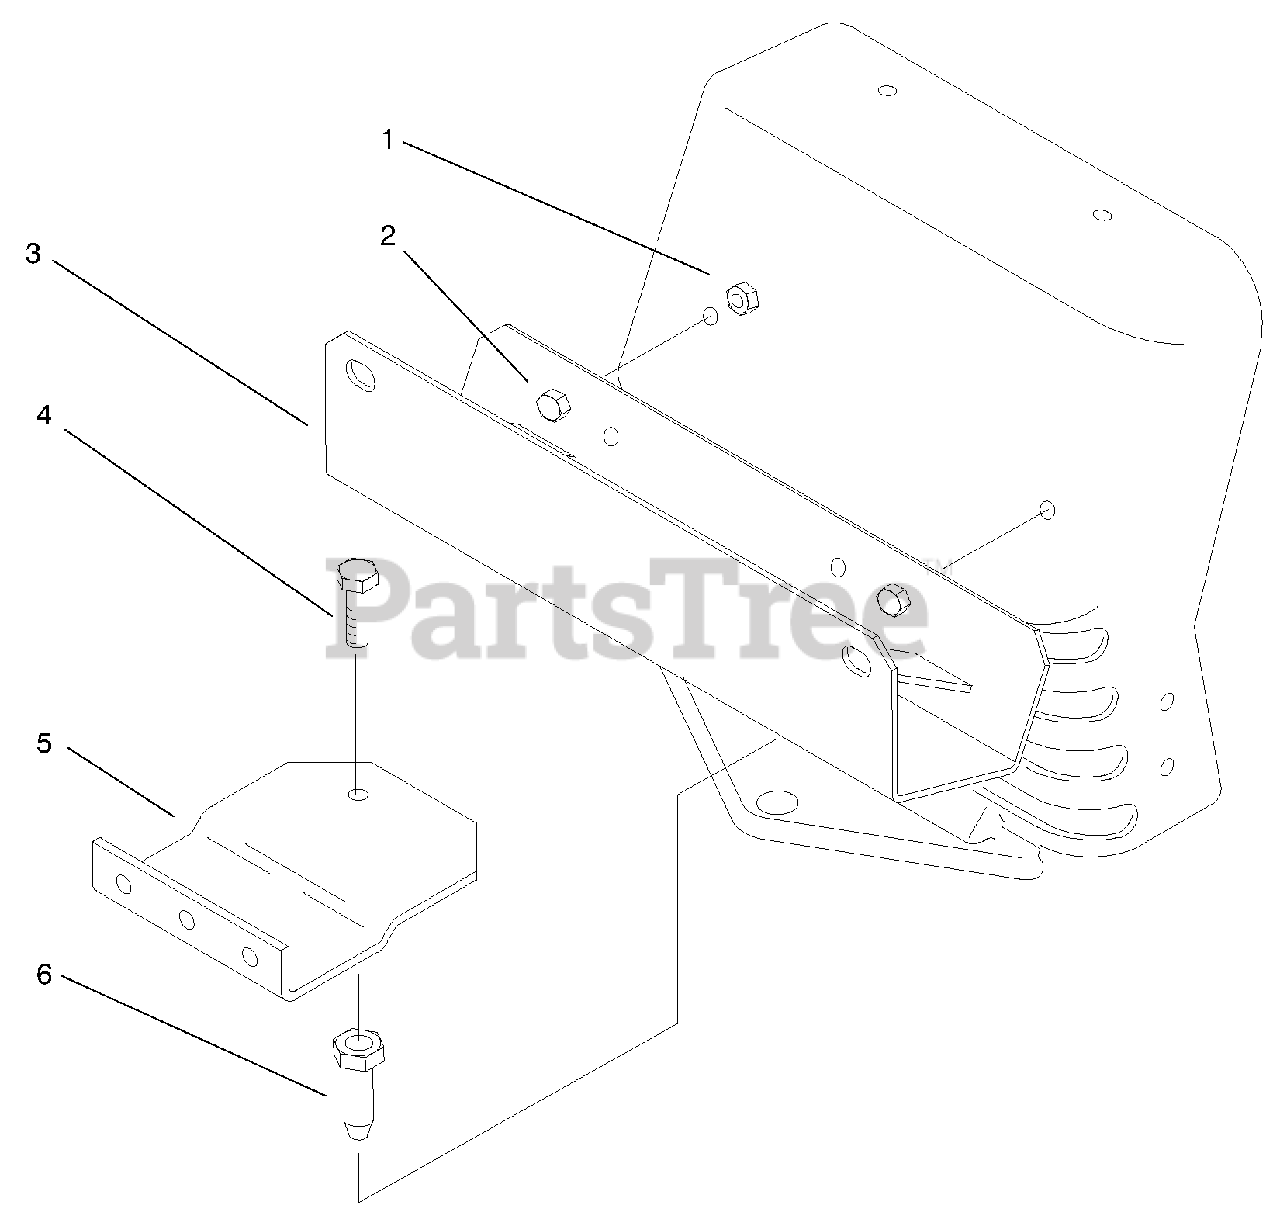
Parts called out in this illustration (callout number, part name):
1	NUT-LOCK, NI
2	SCREW-HH
3	Bracket-Channel
4	SCREW-HH
5	Bracket-Bagger Mounting
6	LOWER MTG PIN
